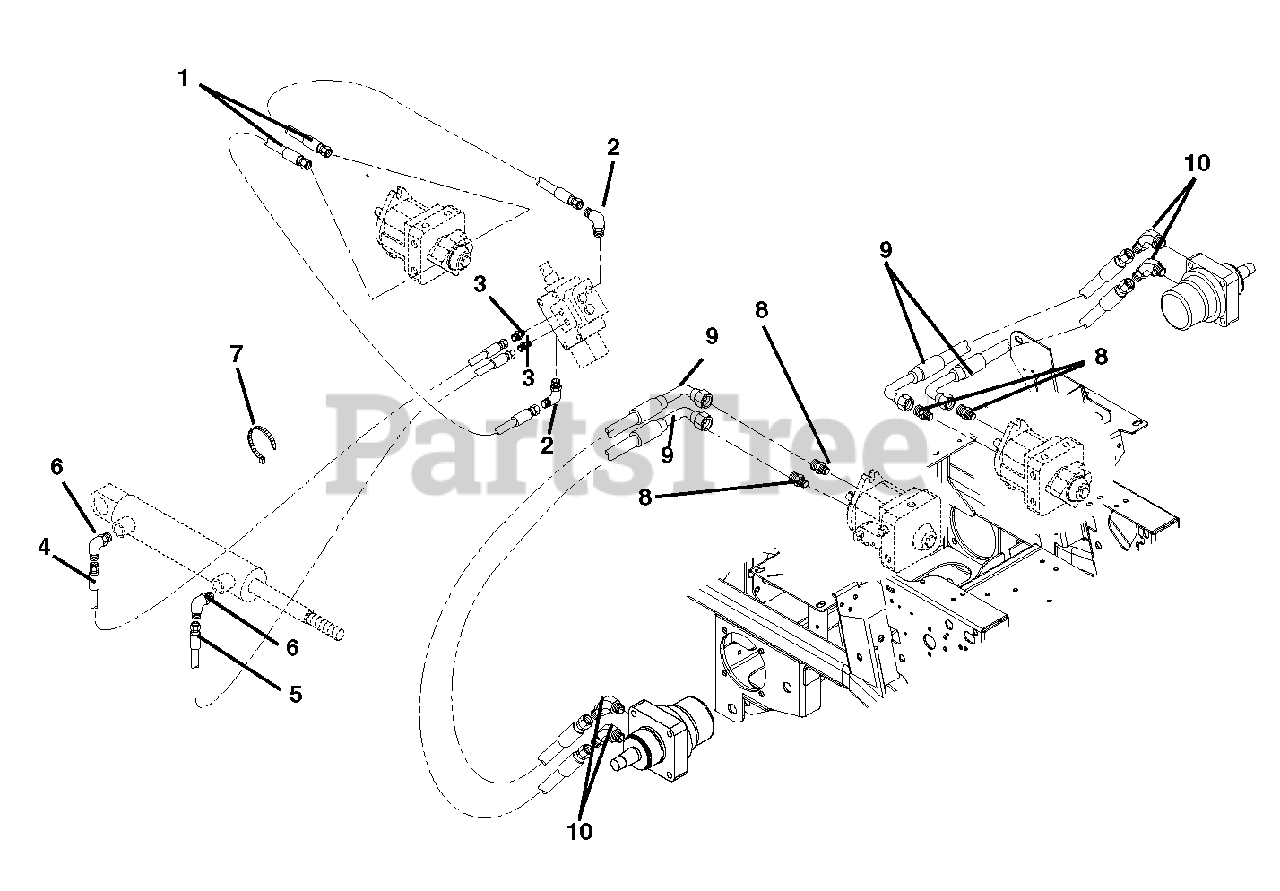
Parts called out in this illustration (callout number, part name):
1	Hose, Hydraulic
2	Fitting, Hydraulic Elbow
3	Adapter (4-6F5OLO)
4	Hose, Hydraulic
5	Hose, Hydraulic
6	Fitting, Hydraulic (4 C5OLO)
7	Cable Tie
8	Adapter, Face Seal 8 x 8 .50 O-Ring
9	Hose, Hydraulic .50
10	Adapter, Hydraulic Steel .875 to .75
